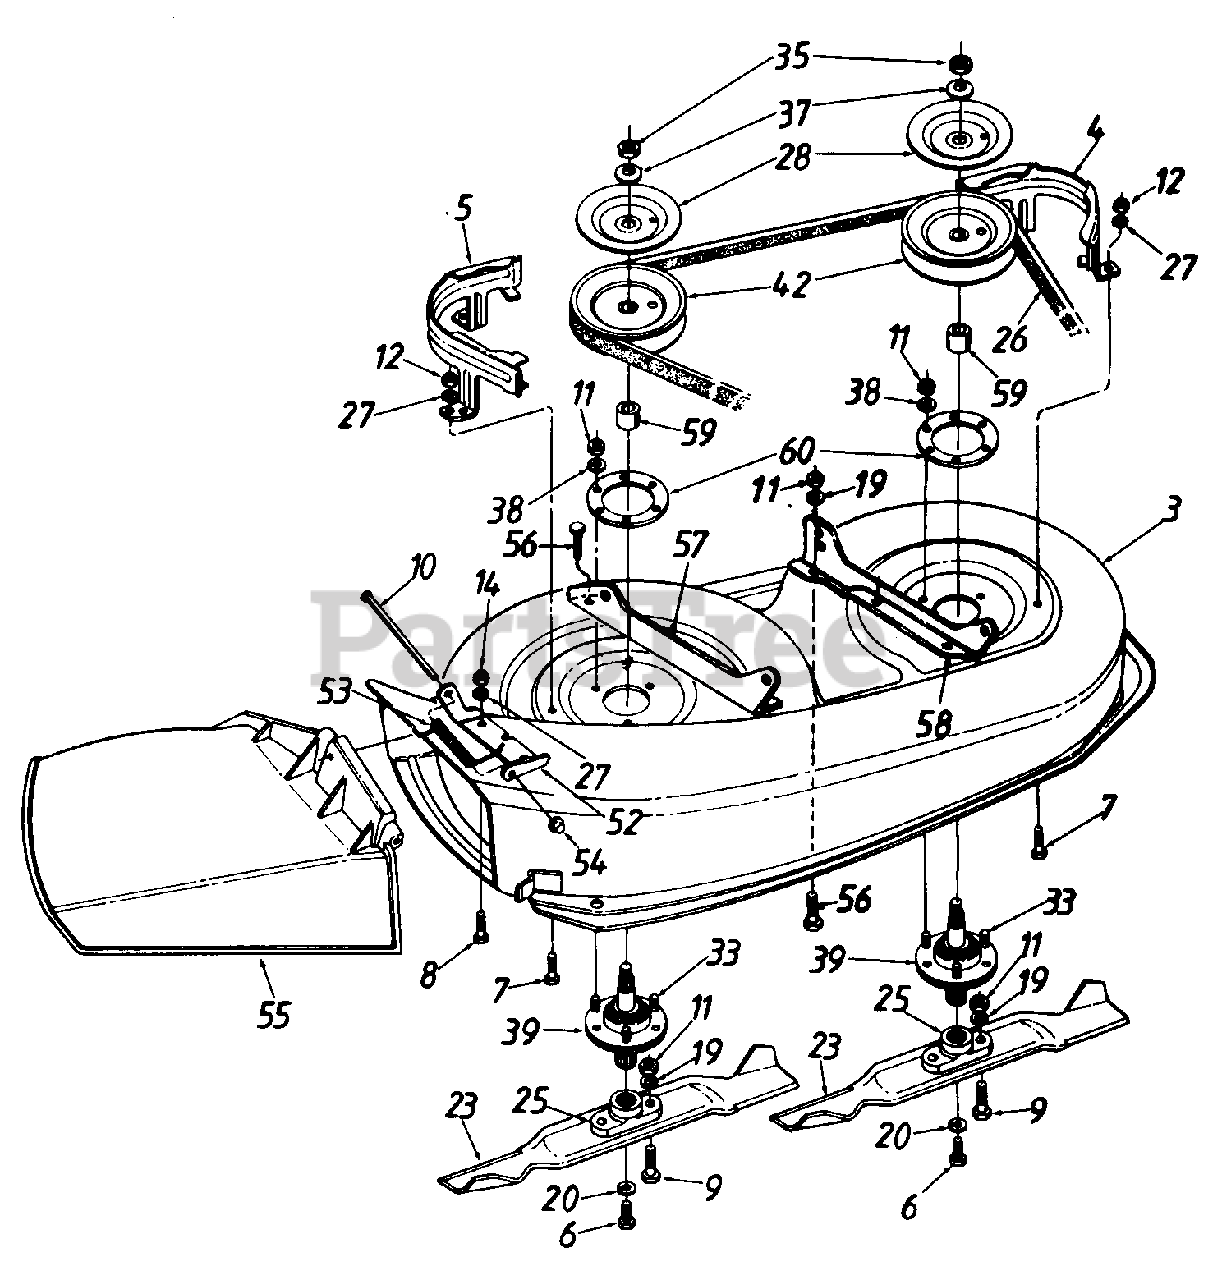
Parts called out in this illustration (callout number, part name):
3	36" Deck Ass'y.
7	Hex Bolt 1/4-28 x .62" Lg.
8	Truss Mach. Scr. 1/4-20 x .75"
9	Hex Bolt Special 5/16-24 x 1.0"
10	Hinge Pin
11	Hex Nut 5/16-24 Thd.
12	Hex Nut 1/4-28 Thd.
14	Hex Nut 1/4-20 Thd.
19	L-Wash. 5/16" I.D.
20	L-Wash. 3/8" I.D.-H.D.
23	High-Lift Blade
25	Blade Adapter
26	"V"-Belt
27	Bell-Wash. 1/4" I.D.
28	Brake Disc
33	Rib Neck Bolt 5/16-24 x .84" Lg.
35	Hex Jam Nut 5/8-18 Thd.
37	L-Wash. 5/8" I.D.
38	L-Wash. 5/16" I.D.
39	Blade Spindle Ass'y. Comp.
42	5" Dia. Pulley
52	Hinge Mtg. Brkt.
53	Torsion Spring
55	Chute Ass'y. Comp.
56	Hex Bolt 5/16-24 x .75" Lg.
60	Reinforcement Plate
